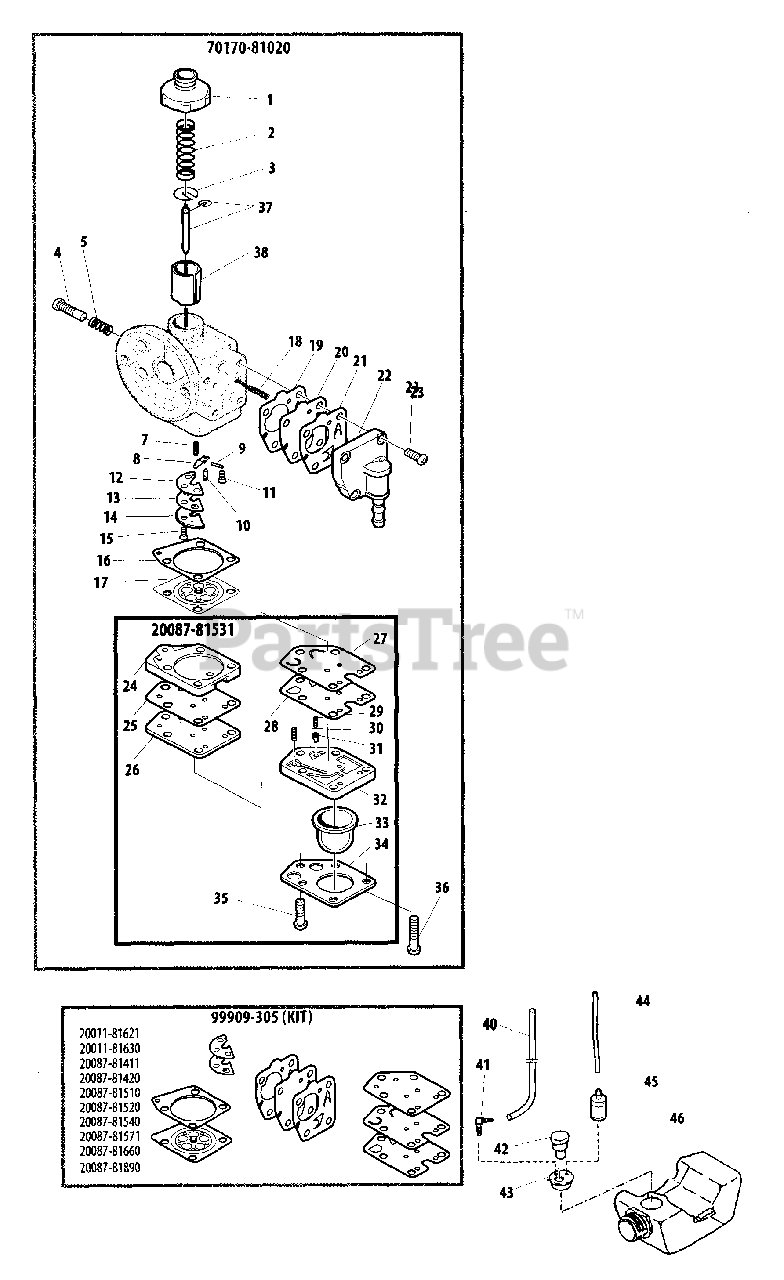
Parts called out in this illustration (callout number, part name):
1	CAP, CARBURETOR
2	SPRING
3	RETAINER
4	SCREW, IDLE ADJUST
5	SPRING
7	SPRING
8	LEVER, METERING
9	PIN, METERING LEVER
10	VALVE, INLET NEEDLE
11	SCREW, METERING LEVER PIN
12	GASKET
13	VALVE, CHECK
14	PLATE
15	SCREW, METERING LEVER PIN
16	GASKET, METERING
17	DIAPHRAGM, METERING
18	SPRING
19	GASKET, METERING
20	DIAPHRAGM, METERING
21	VALVE, PUMP
22	BODY, PUMP
23	SCREW
24	BASE, PURGE
25	GASKET
26	PLATE, PUMP
27	DIAPHRAGM
28	GASKET
29	SPRING, RETURN
30	SPRING
31	VALVE
32	COVER, PUMP
33	BULB, PURGE
34	PLATE
35	SCREW
36	SCREW
37	NEEDLE, JET
38	SLIDE VALVE
40	PIPE - RETURN
41	CONNECTOR, PIPE
42	VENT, FUEL TANK
43	GROMMET
44	PIPE - FUEL
45	FILTER, FUEL
46	TANK, FUEL
